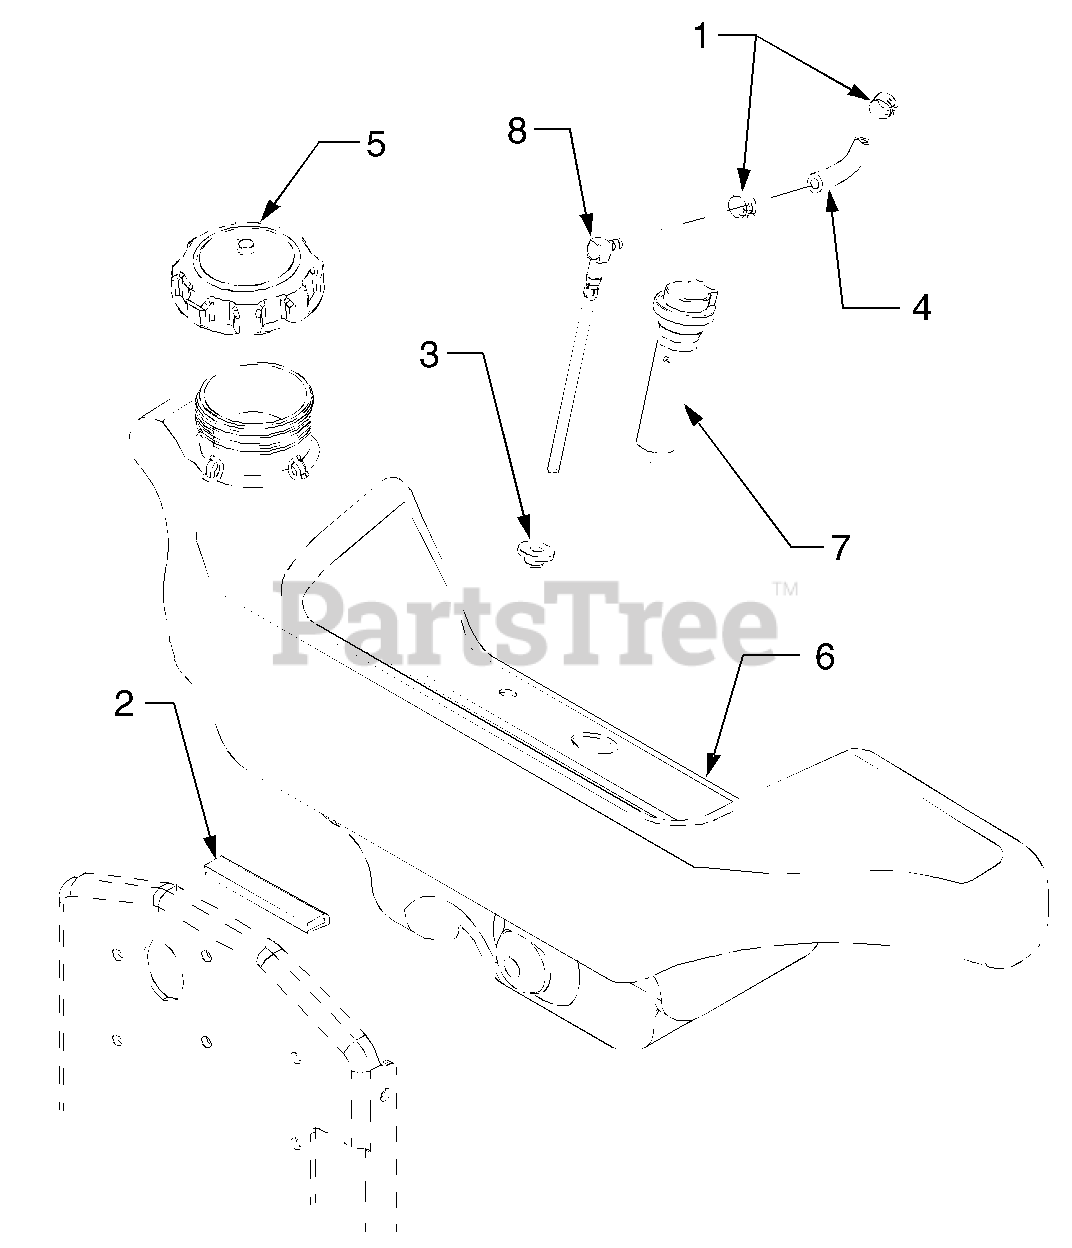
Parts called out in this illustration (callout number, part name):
1	Clamp, Hose
2	Trim, Tank Protector
3	Bushing, Rubber
4	Fuel Line
5	Cap, Fuel
6	Tank, Fuel, 4.5 Gallon
7	Sensor, Low Fuel
8	Fitting, Fuel Pickup
